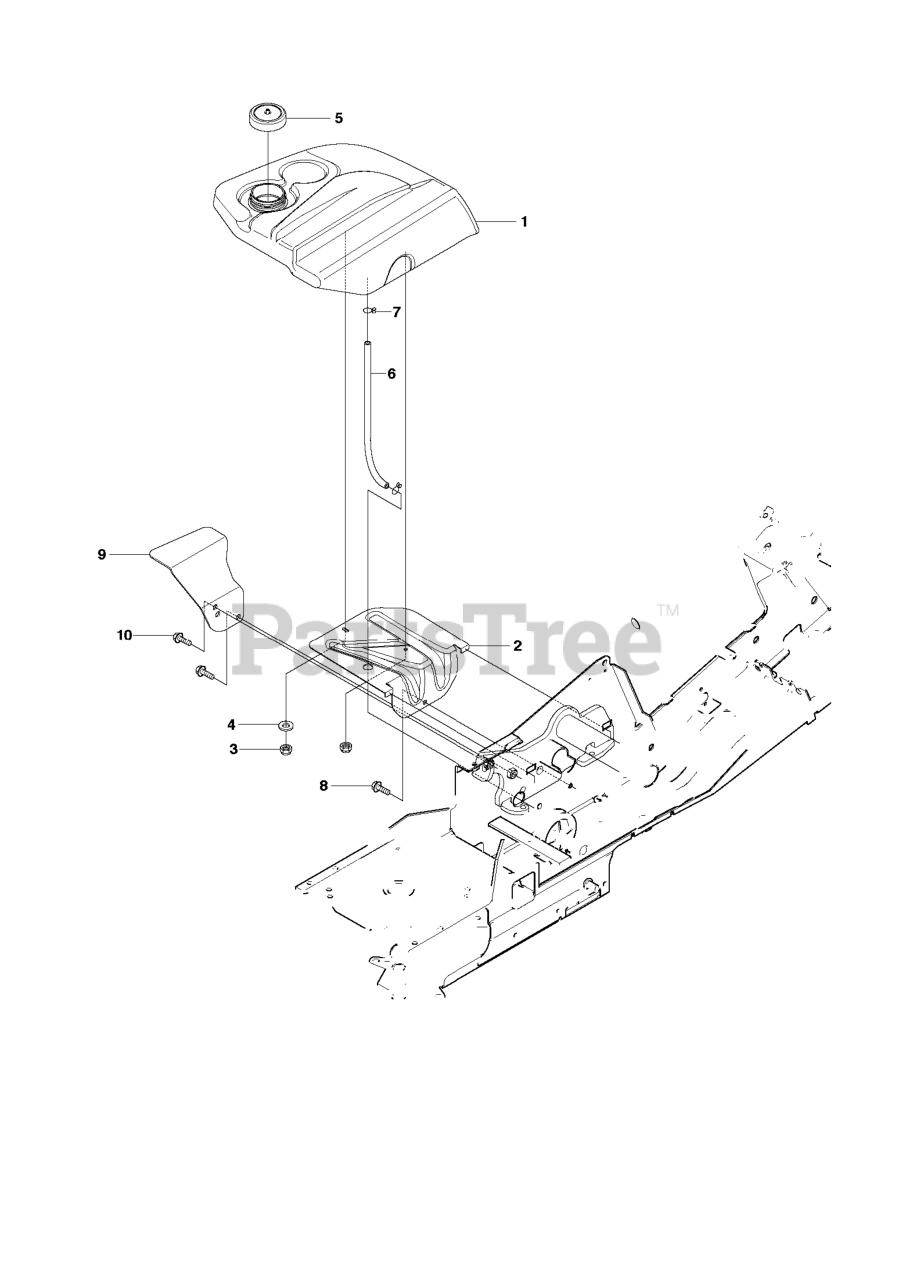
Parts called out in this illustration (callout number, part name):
3	LOCKNUT M6
4	WASHER
10	Screw M10x25
